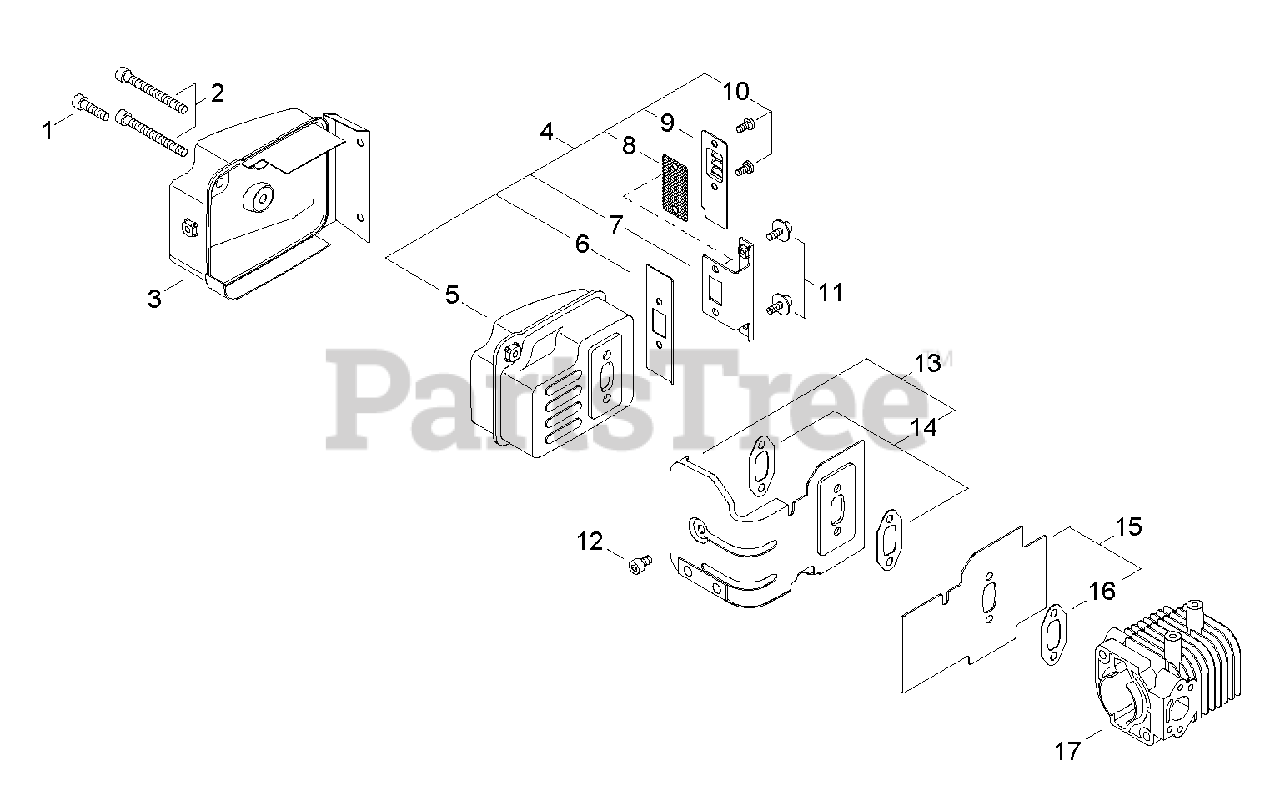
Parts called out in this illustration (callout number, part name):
1	SCREW - 5X20
2	SCREW - 5
3	COVER, MUFFLER
4	MUFFLER ASSY
5	MUFFLER
7	BRACKET, MUFFLER
8	SCREEN, SPARK ARRESTOR
9	GUIDE, EXHAUST
10	SCREW - 4X8
11	SCREW - 4X8
12	SCREW - 5X8
13	HEAT SHIELD KIT
14	HEAT SHIELD KIT
15	EXHAUST SHIELD KIT
16	HEAT SHIELD KIT
17	CYLINDER
